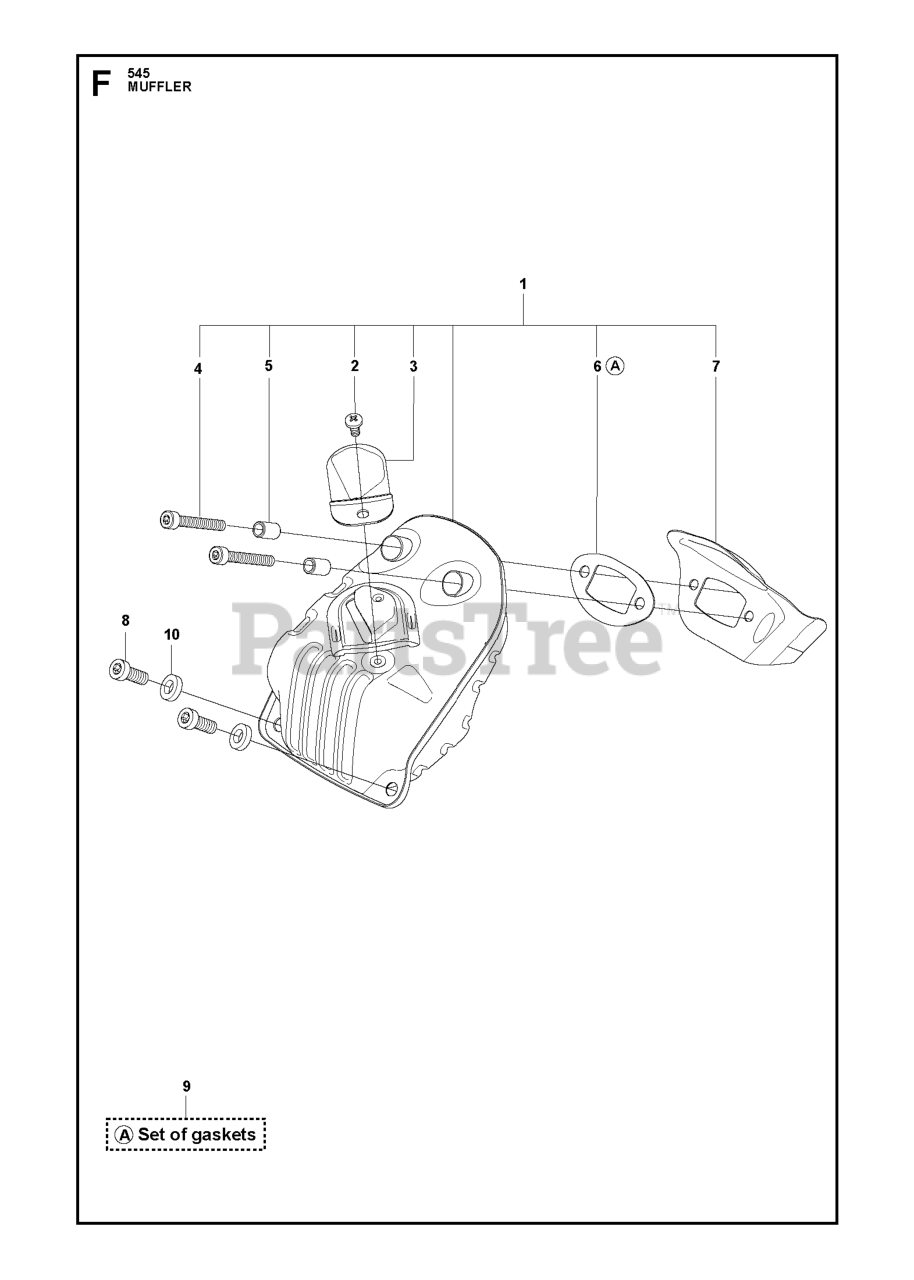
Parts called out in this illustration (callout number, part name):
1	MUFFLER KIT
3	SPARK ARRESTER A004 50 CC
4	SCREW ITXSCM M6X35 T27 12.9 T
6	GASKET MUFFLER
7	HEAT DEFLECTOR
8	SCREW ITXSCM M6X20 T27 10.9 Z
9	GASKET KIT 50CC
